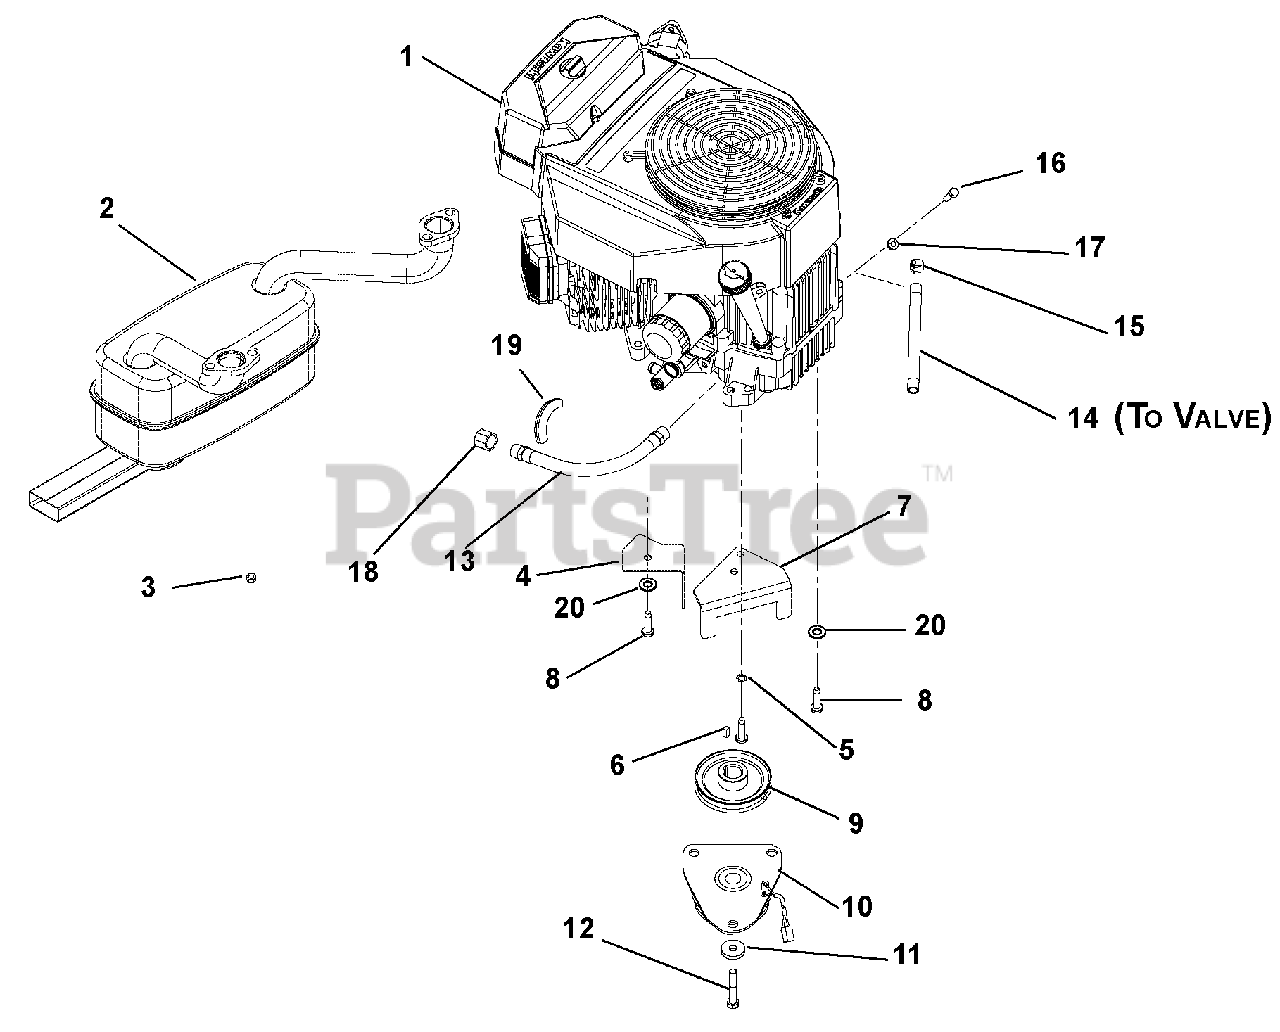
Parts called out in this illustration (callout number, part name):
1	Engine, Kawasaki FR 651 (991090, 098)
1	Engine, Kawasaki FR 691 (991082, 083, 099, 100)
1	Engine, Kawasaki FR 730 (991084, 101)
1	Engine, Kohler Twin - 24 HP Pro (991107)
1	Engine, Kohler Twin - 25 HP Pro (991108, 109)
1	Engine, Kohler Twin - 26 HP Pro (991110)
2	Muffler, Kawasaki Engine (991082, 083, 084, 090, 098, 099, 100, 101)
2	Muffler, Kohler (991107, 108, 109, 110)
3	Nut, Locking Top M8-1.25
4	Guard, Clutch Wire
5	Washer, Locking, Extension .391 x .682 x .036
6	Key, Square .25 x .625 x .25 SAE 8630 OR SAE 1035
7	Anchor, Ogura Clutch
8	Bolt Hex .38-16 x 1.25 G5YZ NYTORQ
9	Pulley, 4.50 OD x 1.002 Engine
10	Clutch Assembly, Ogura
11	Washer, Flat Steel .469 x 2.00 x .25
12	Bolt, Hex .44-20 x 2.75 Grade 5
13	Hose, Hydraulic .38-11-0K M6N0-F6J0
14	Hose, Gas Line Low Perm
15	Clamp, Fuel Line
16	Bolt, Hex M8-1.25 x 2.00
17	Washer, Locking .31 x .098 Regular
18	Pipe Cap, 3/8 NPT Female
19	Protector, Oil Draw Hose
20	Washer, 3/8" Spring Disc
